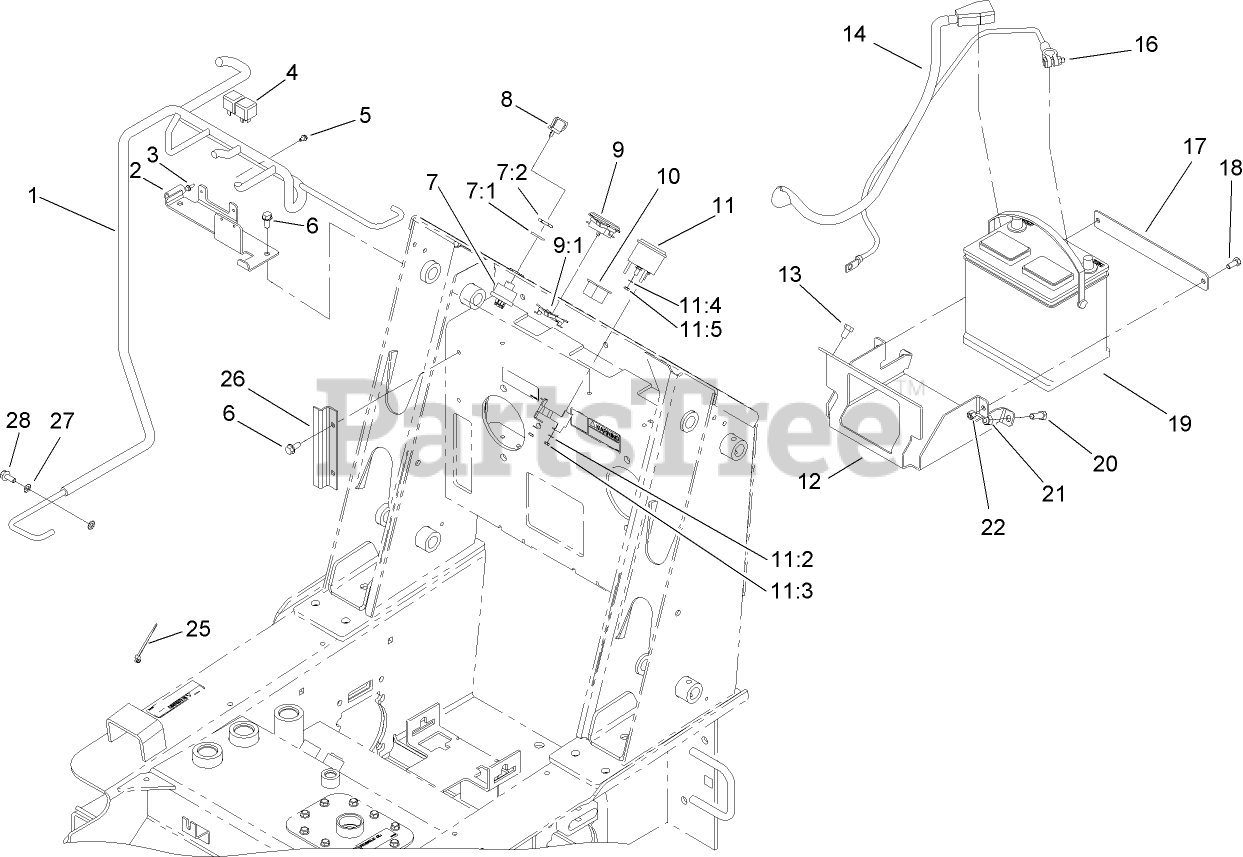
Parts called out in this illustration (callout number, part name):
1	HARNESS-WIRE
2	Fuse/Relay Bracket ASM
3	SCREW-HWH
4	RELAY
5	SCREW-HWH
6	SCREW-HWHTF
7	Key Switch ASM
7:1	WASHER-TOOTH, INTERNAL
7:2	NUT-HH
8	KEY-IGNITION
9	INDUCTIVE HOURMETER ASM
9:1	CLIP-MOUNTING
10	PLUG-HOLE
11	GAUGE-FUEL
11:2	WASHER-LOCK, INT
11:3	NUT-HEX
11:4	WASHER-LOCK / EXT
11:5	NUT-HEX
12	TRAY-MOUNTING, BATTERY
13	SCREW-HWHTF
14	CABLE-BATTERY, POSITIVE
16	CABLE-BATTERY, NEGATIVE
17	CLAMP-BATTERY
18	SCREW-HH
19	BATTERY
20	SCREW-HH
21	NUT-LOCK, NI
22	NUT-LOCK, NI
25	TIE-CABLE
26	SHIELD-WIRING
27	WASHER-LOCK
28	SCREW-HHF
